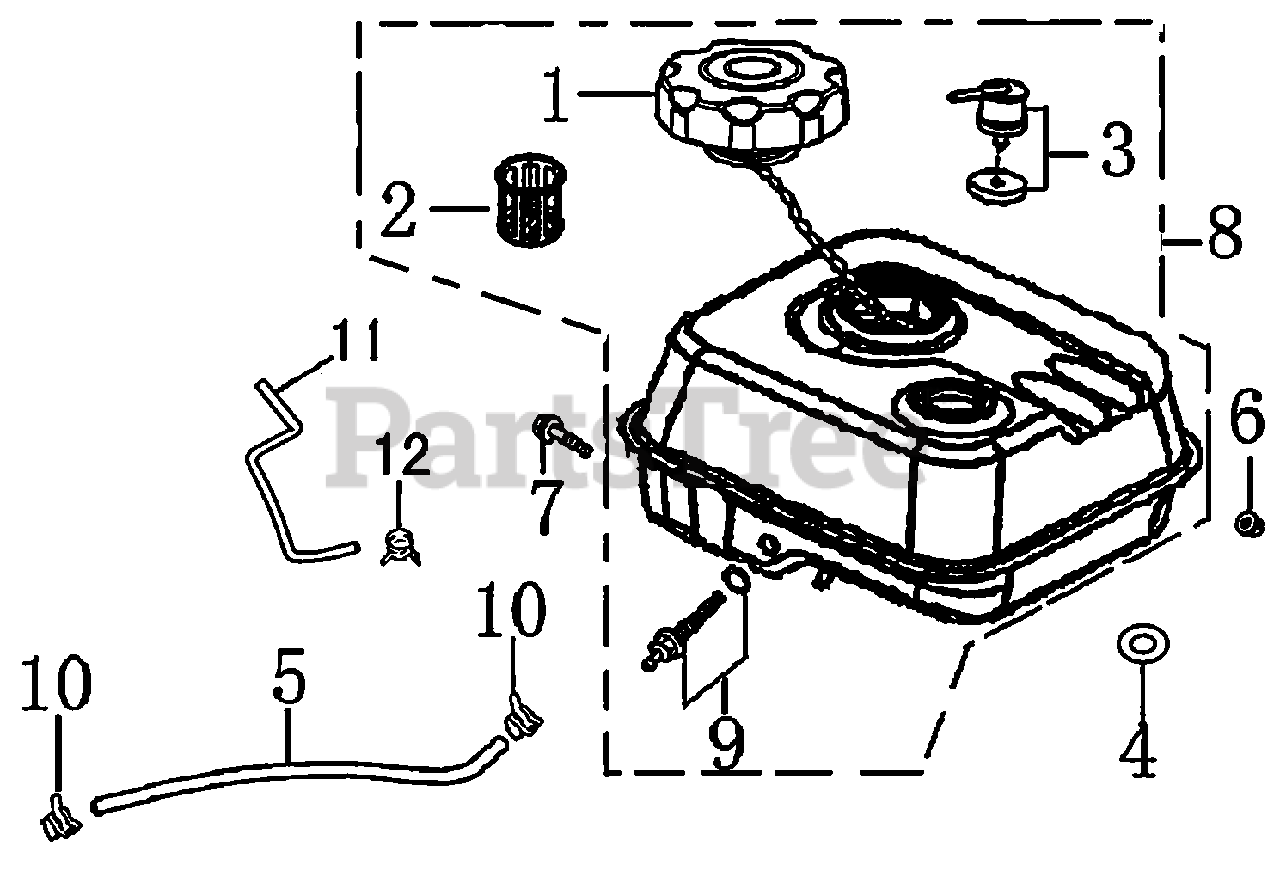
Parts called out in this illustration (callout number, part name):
1	CAP, FUEL FILLER
2	FILTER, FUEL
4	WASHER, RUBBER
5	HOSE, FUEL
6	NUT, FLANGE, 6MM
7	BOLT, FLANGE, 6x25
8	TANK COMP., FUEL
9	JOINT ASSY., FUEL TANK
10	CLAMP/COLLAR
11	FORMED HOSE
